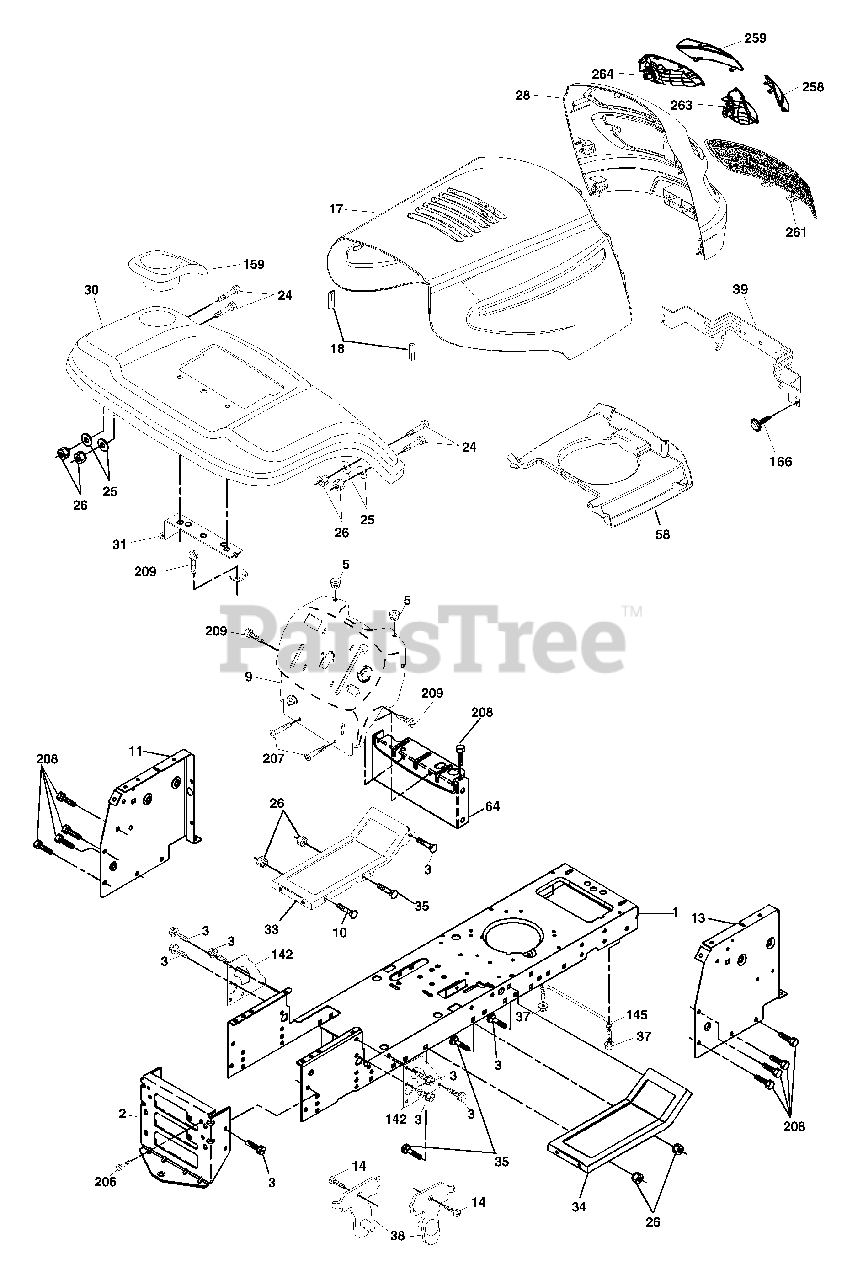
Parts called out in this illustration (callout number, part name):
1	Chassis
2	Drawbar
3	Screw 3/8-16 X .75
5	Bumper Hood/Dash
9	Dash P/L
10	Bolt Carriage 3/8-16 x 1
11	Panel Dash Lh
13	Panel Dash Rh
14	Screw Thdrol 3/8-16 x 1/2
17	Hood
18	Bumper Hood
23	Bushing
24	Bolt Fin Hex 3/8-16 x 1 Gr 5
25	Washer 13/32 X 13/16 X 12 Ga
26	Nut Lock Hex W/Ins 3/8-16 Unc
28	Grille/Lens Asm
30	Fender Footrest STLT Pnt
31	Bracket Fender
33	Footrest Pnt Lh
34	Footrest Pnt Rh
35	Bolt Rdhd Sht Sqnk 3/8-16 x 3/4
37	Screw Thdrol 6/16-18 x 1/2 TYT
38	Bracket Asm Pivot Mower Rear
39	Bracket Pivot
58	Duct Air
64	Dash Lower STLT
142	Plate Reinforcement STLT
145	Rod Pivot Chassis/Hood
159	Cupholder
166	Screw Hwhd Hi-Lo #13-16 x 3/4
206	Bolt Shoulder 5/16-18
207	Screw Thdrol 5/16-18 x 1/2
208	Screw Thdrol 3/8-16 x 1/2
209	Screw Hexwsh Thdr 3/8-16 x 3/4
258	Lens Grille Pro RH
259	Lens Grille Pro LH
263	Bezel Grille LH
264	Bezel Grille RH
